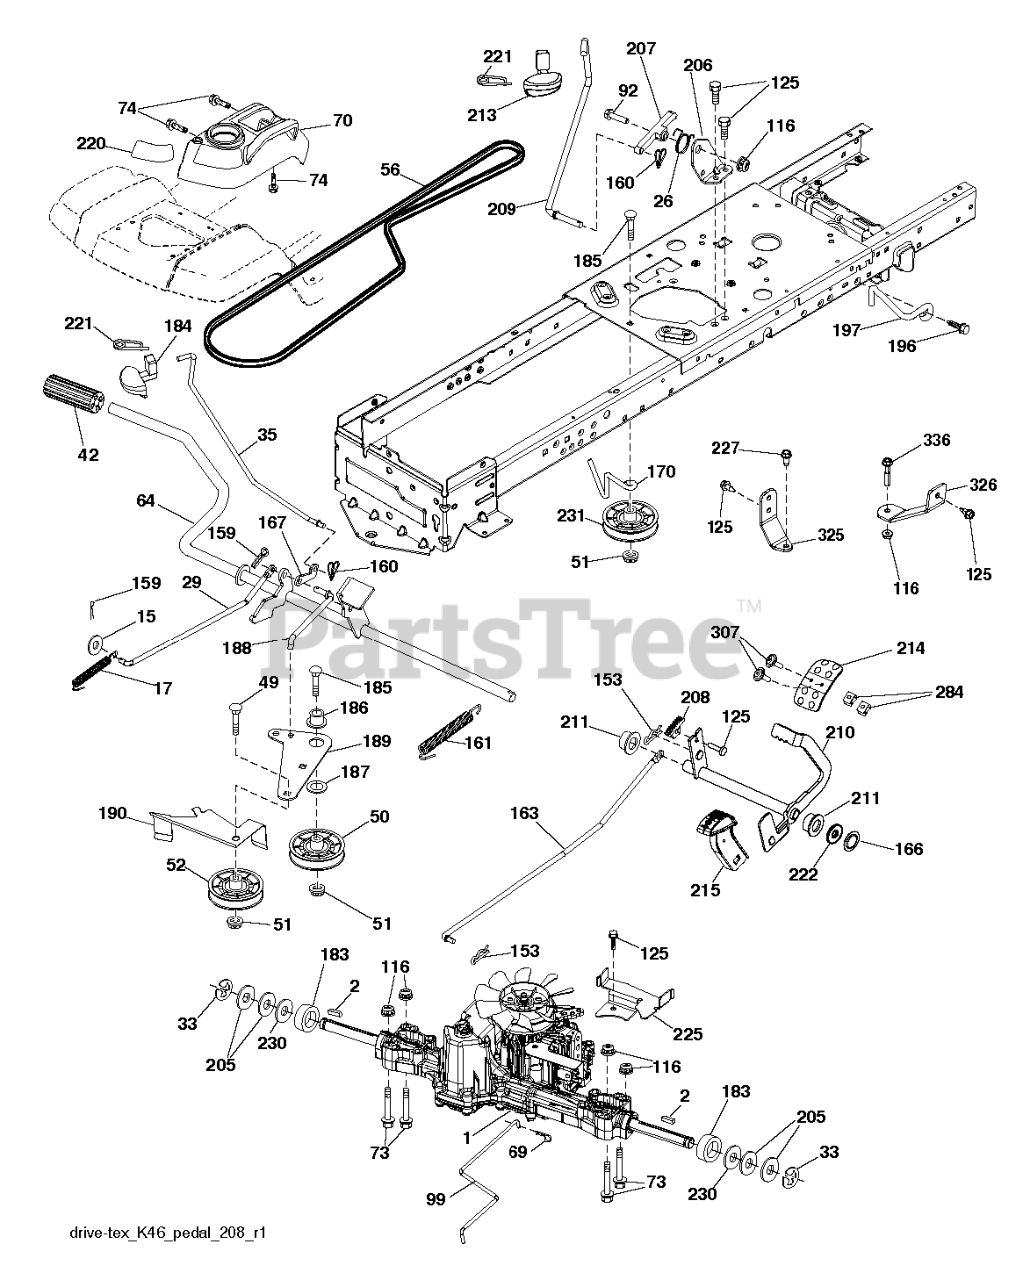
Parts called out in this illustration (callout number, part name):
2	SQUARE KEY
15	WASHER
17	SPRING.BRAKE.K46.GREEN
26	SPRING.RETURN.CRUISE
29	ROD.BRAKE.K46
33	E RING HYT
35	ROD .BRAKE. PARKING. GT. HUSQ.
42	PEDAL COVER T
50	IDLER.FLAT.910.OFFSET
51	NUT LOCK FLG 3/8-16 UNC
52	IDLER.V-GROOVE.910.OFFSET
56	V-BELT.MOWER.92.40.42/K46
64	SHAFT.ASM.PEDAL.BRK.CNTR
70	CONSOLE.ASM.RH.GT.FC.HUSQ
73	BOLT
74	SCREW.HI-LO.CONSOLE
92	BOLT
99	ROD.SPRING.BYPASS.K46.LT.Z
116	NUT LOCK HEX FLANGE 5/16-18
125	SCREW
153	RETAINER M
159	COTTER PIN
160	RETAINER CLIP
161	SPRING, RETURN LT
163	ROD.CONTROL.K57R.K46
166	NUT.PUSH.625
167	LATCH.BRAKE.SPRING
170	KEEPER.CENTER SPAN.1.688
183	SPACER AXLE
184	HANDLE.PARKING.BRAKE.H (BLK)
186	SPACER.RETAINER
187	WASHER 12/32X2X10GA
188	RP.LINK.CLUTCH.GROUND.DRIVE
189	BELLCRANK.GROUND.DRIVE.TEX.
190	KEEPER.BELLCRANK.DRIVE
196	SCREW 3/8-16X1
197	BRKT.42.FCS.CLUTCH.ANTIROTATIO
206	BRACKET.MOUNT.CRUISE.LATCH
207	LATCH.CONTROL.CRUISE.TEX
208	GEAR.SECTOR.CONTROL.CR
209	ROD.CONTROL.CRUISE.GT.
210	ROCKER.ASM.PEDAL.CONTR
211	BEARING.NYLON
213	KNOB.CONTROL.CRUSIE.HU
214	PEDAL.FORWARD.HUSQVARNA.DEALER
215	PEDAL.COVER.REVERSE.CRD.X428BK
220	REFLECTOR.RH.TEX GT
221	RETAINER.SPRING.CLIP.H
222	WASHER 21/32 X 1-1/4 X 10 GA.
225	KEEPER.BELT.TRANSAXLE.K46
227	SCREW.THDROL.5/16-18X3/4.TTY
230	WASHER.HARDENED
231	IDLER.V-GROOVE.1.688.OFFSET
284	NUT.U-CHNL.1/4-20.550DP.350PNL
307	SCREW.MACHINE.CR.1/4-20
325	TORQUE.STRAP.K46.LT.LH
326	BRACKET.TRQ.STP.K46.18"TIRE.RH
336	BOLT.5/16-18X1-3/4.FLANGED.HEX
